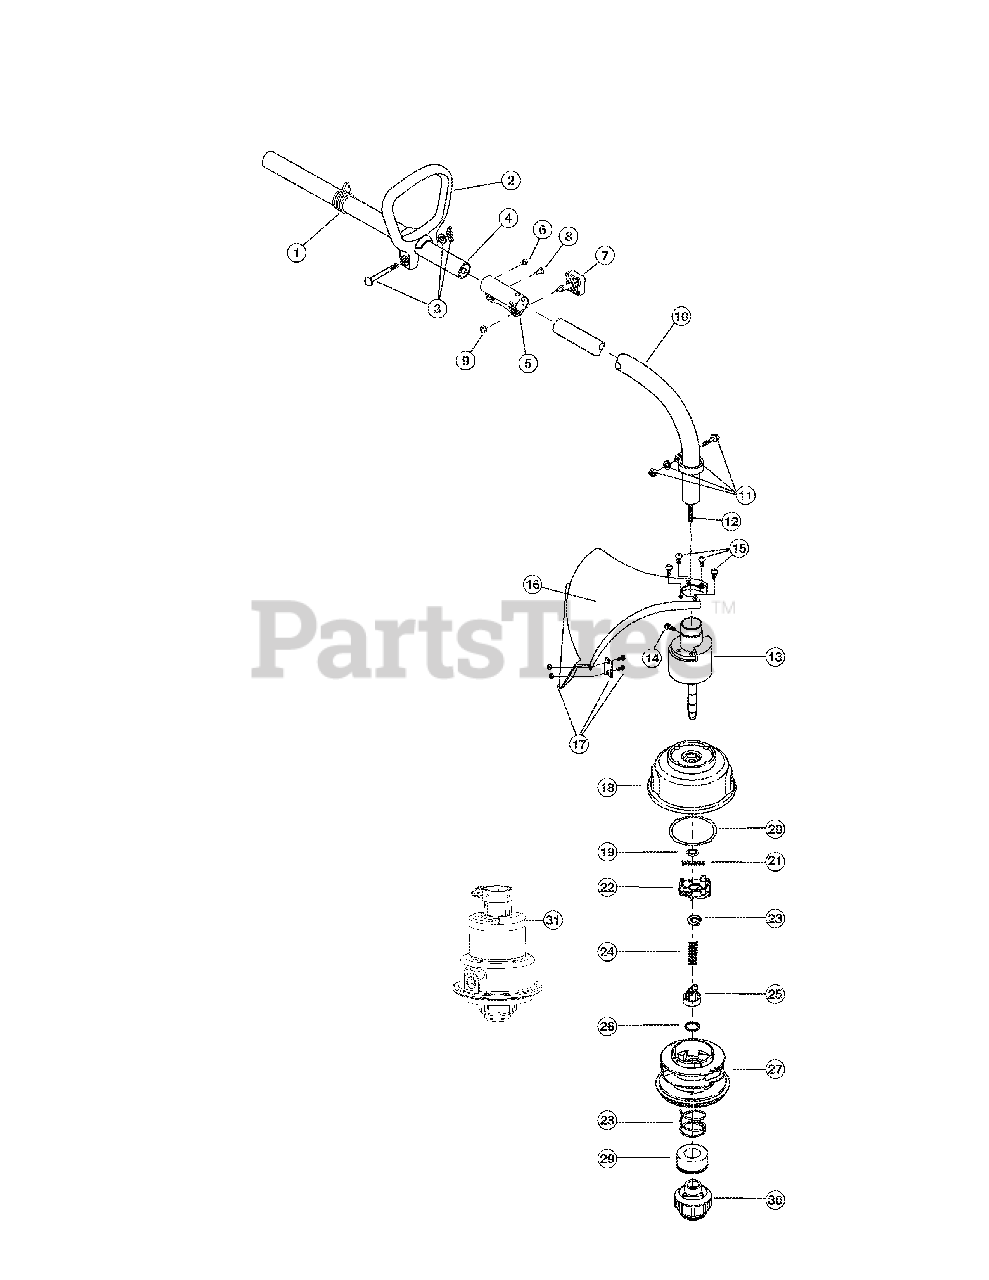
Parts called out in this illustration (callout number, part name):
1	Shoulder Harness Clamp
2	D-Handle (includes 3)
3	D-Handle Hardware Assembly
4	Upper Drive Shaft Housing Assembly
5	Split Boom Coupler (includes 6-9)
7	Adjustment Knob
9	Nut
10	Lower Drive Shaft Assembly
11	Lower Clamp Assembly
12	Flexible Drive Shaft
13	Bushing Housing Assembly
14	Anti-Rotation Screw
15	Guard Mounting Screws
16	Guard Assembly (includes 17)
17	Blade Assembly
18	Outer Spool Assembly (includes 19)
19	Retainer
20	Thrust Washer
21	Small Spring
22	Slider
25	Plunger
27	Inner Reel
28	Large Spring
29	Foam Seal
30	Bump Head Knob Assembly (includes 28 & 29)
31	Complete Cutting Head Assembly (includes 11 & 13-30)
